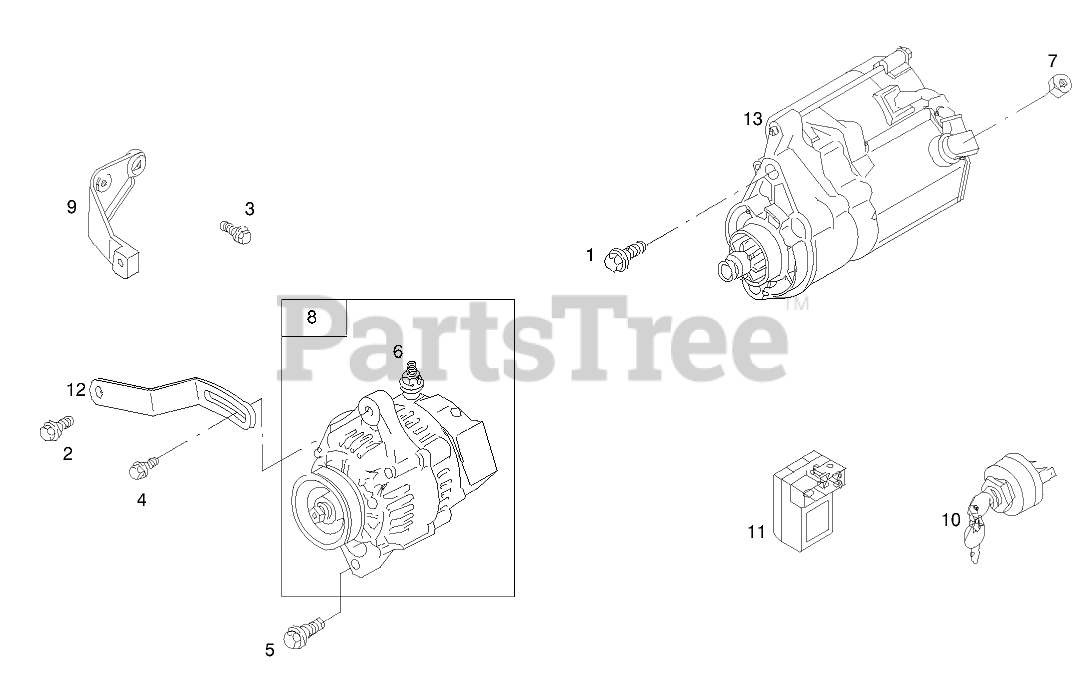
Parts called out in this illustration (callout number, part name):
1	SCREW-HEX
2	SCREW-HEX
3	SCREW-HEX
4	SCREW-HEX, METRIC
4	NIPPLE ASM
5	SCREW-HEX, METRIC
5	VALVE ASM
6	NUT-HEX, METRIC
7	NUT-HEX, METRIC
8	ALTERNATOR
9	BRACKET-SUPPORT
9	GASKET-SET
10	KEY SWITCH
11	MODULE
12	BRACKET-ADJUSTING
13	MOTOR-STARTER
14	VALVE OVERHAUL KIT
15	SHAFT-GEAR
